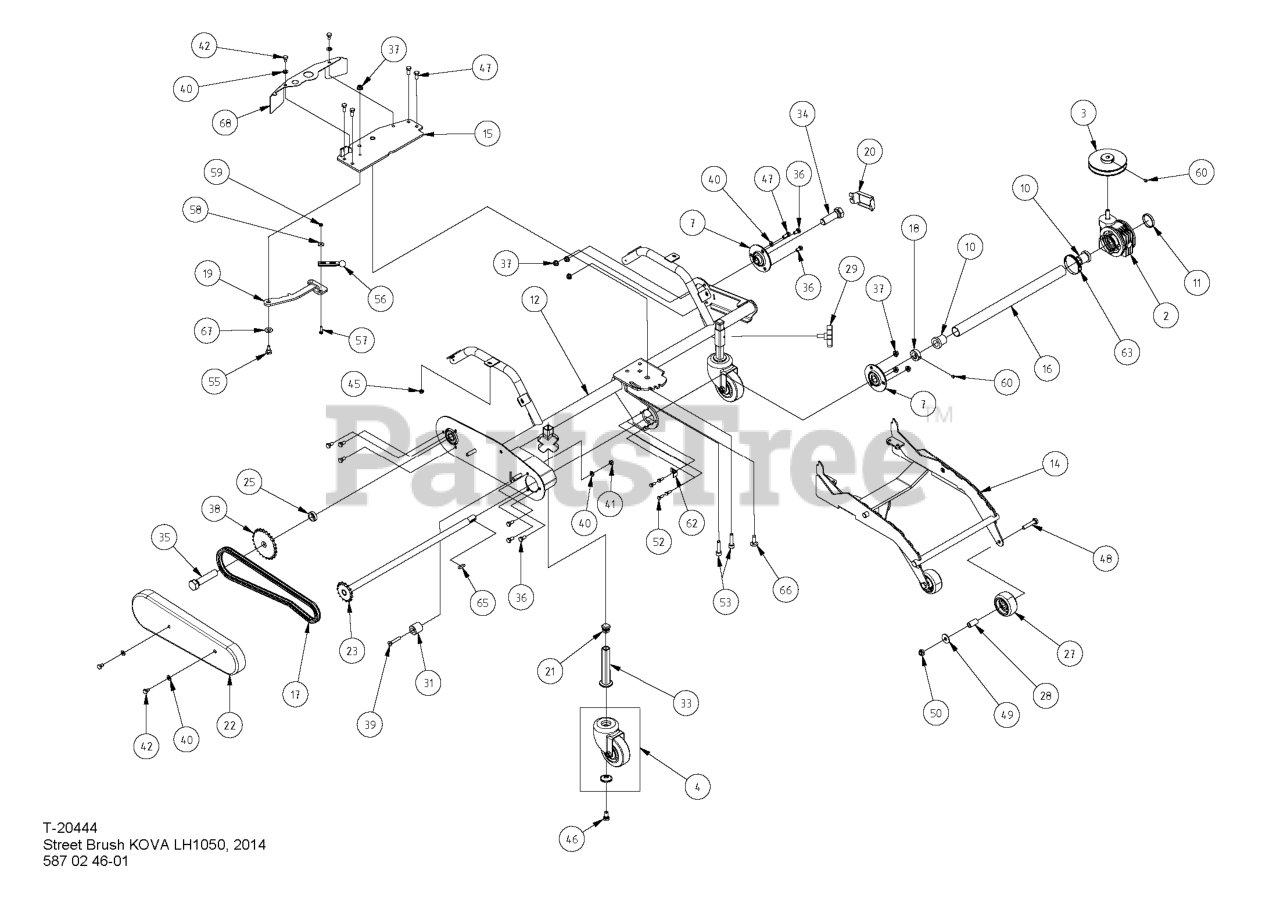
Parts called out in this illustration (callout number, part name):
4	SUPPORT WHEEL
14	FRAME BRACKET
23	DRIVE SHAFT
27	SUPPORT WHEEL
28	COLLAR
31	CHAIN ADJUSTER
37	NUT LOCKING
38	GEAR WHEEL
56	Support Strap
